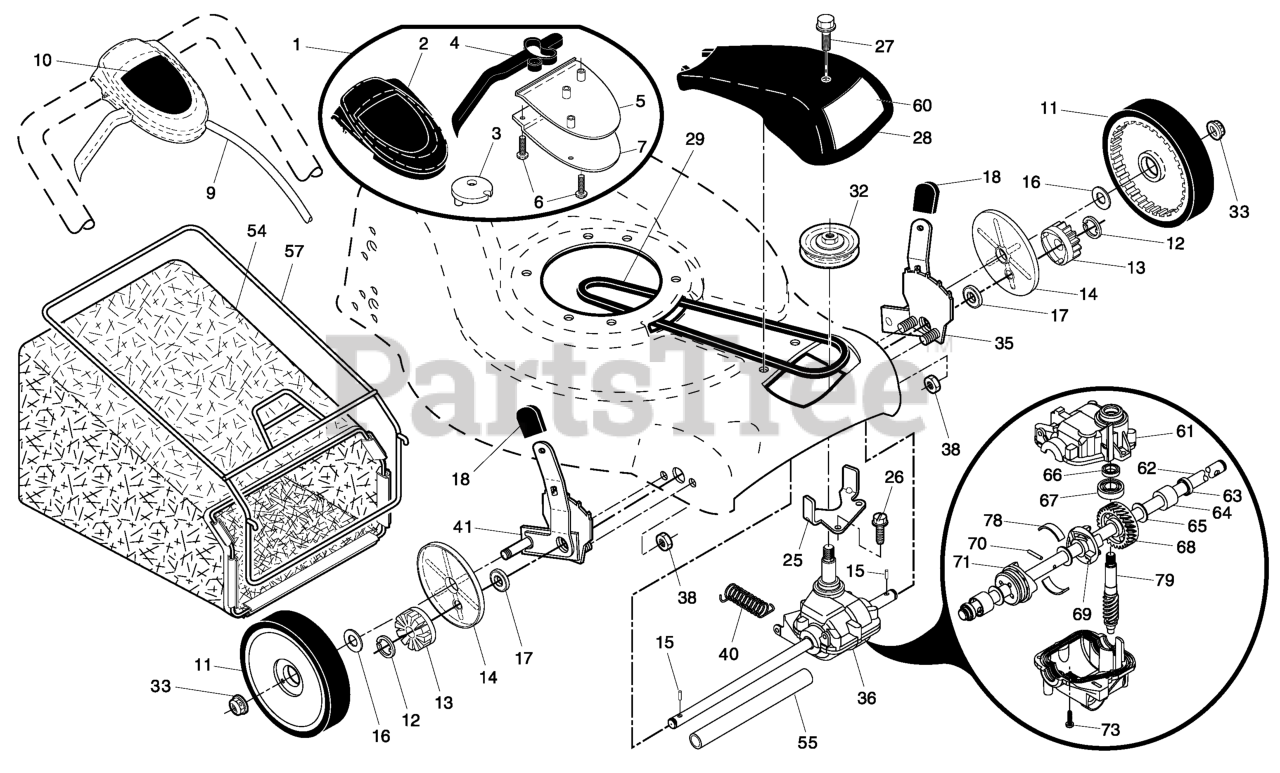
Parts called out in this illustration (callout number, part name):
1	DRIVE CONTROL ASSEMBLY (INCLUD
2	COVER TOP AUTO WALK CONTROL
3	PULLEY
4	LEVER, AUTOWALK DRIVE CONTROL
5	COVER BOTTOM AUTO WLK CONTROL
6	SCREW, PHILLIPS HEAD 10 X 5/8
7	BRACKET.DRIVE.CONTROL.MOUNT.BL
9	CABLE ASSEMBLY, DRIVE
10	DECAL, DRIVE
11	WHEEL.8X1.75.H3SPK.RAD3.GY.BU3
12	E-RING 7/16 RE
13	PINION.14.TEETH.FGD
14	COVER.DUST.WHEEL
15	PAWL, DRIVE
16	WASHER FLUT
17	BEARING
18	KNOB.DELUXE.GRAY
25	BELT KEEPER
27	SCREW, HEX HD TAPPING #10-24 1
28	COVER.DR.21.FWGD/B&S.GRAY
29	BELT.DRIVE.FG
32	RP PULLEY.DRIVE.EZ
33	HEX FLANGE LOCKNT
35	WHEEL ADJ KIT LH
36	TRANSMISSION.21.FGD.HT.VST
38	LOCKNUT.NYLOC.1/4-20
41	WHEEL ADJ KIT RH
54	GBAG.34710247.SILVER.H
55	DRIVESHAFT COVER
57	FRAME, GRASSBAG
60	DECAL DRIVE COVER
61	CASE.UPPER.00254(SERVICE)
62	SHAFT OUTPUT (12289)
63	SEAL.OUTPUT.SHAFT
66	SEAL INPUT SHAFT
68	GEAR 28 TEETH 36208
69	FIXED DOG CLUTCH
70	PIN.3.50.33733
71	MOVEABLE DOG CLUTCH
74	CASE.BOTTOM.
78	SPRING LEAF
79	SHAFT WORM
